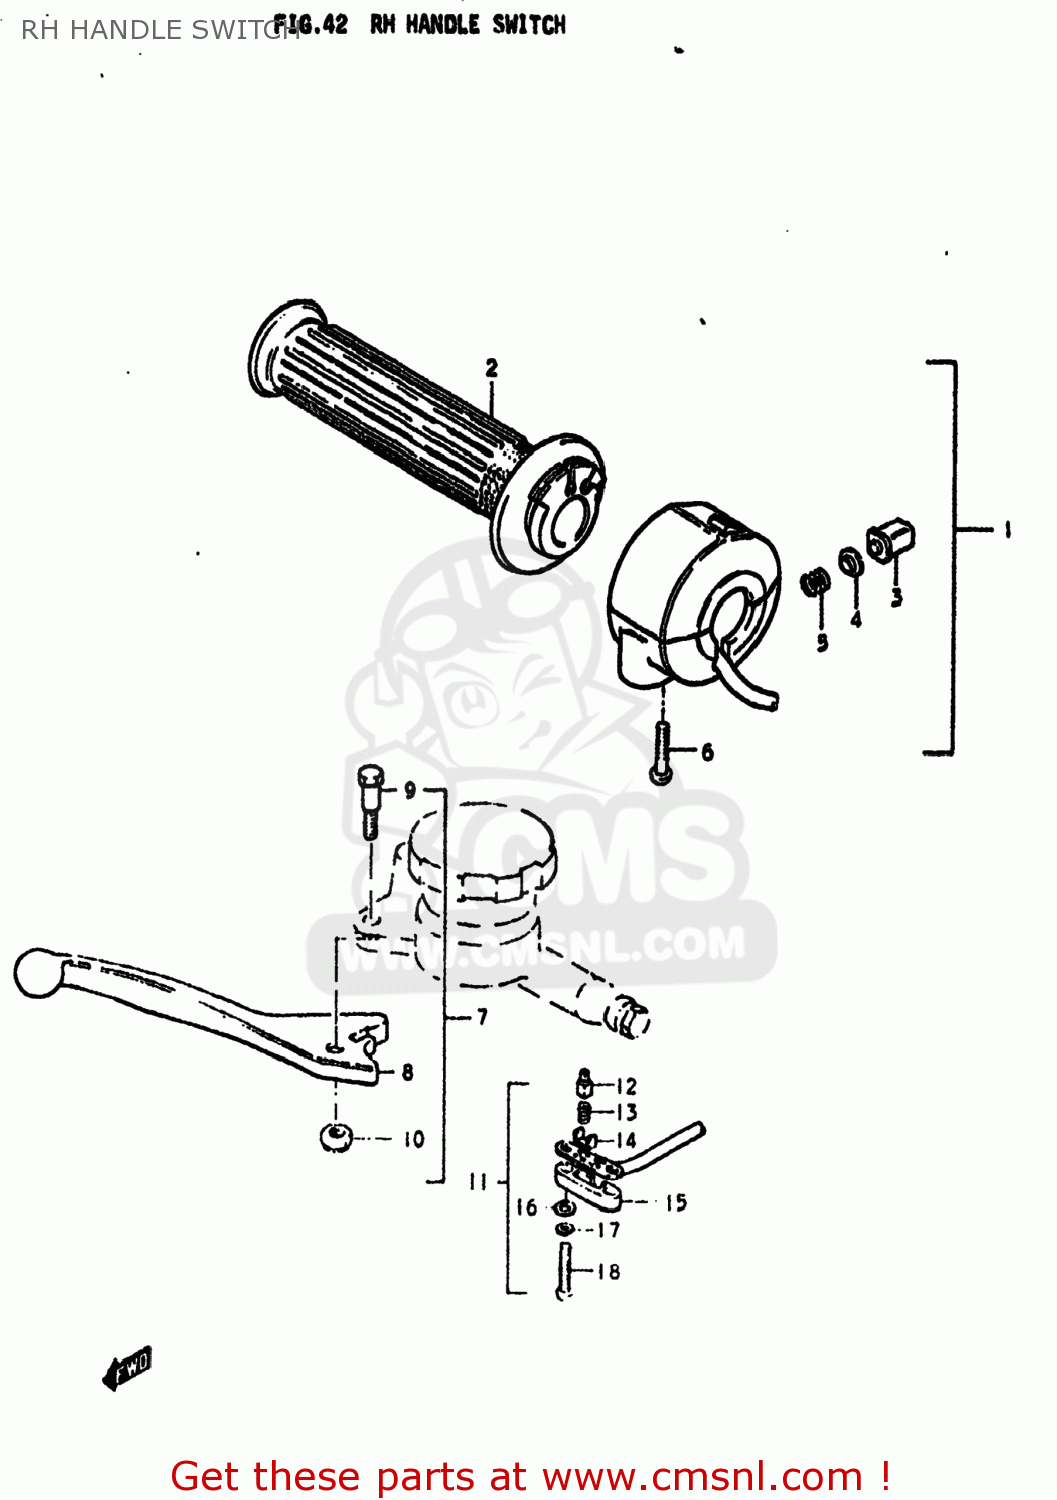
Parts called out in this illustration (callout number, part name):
1	CASE ASSEMBLY,THROTTLE
2	GRIP,THROTTLE
3	BUTTON,HORN
4	CONTACT
5	SPRING
6	SCREW
7	LEVER ASSEMBLY,BRAKE
8	LEVER,BRAKE
9	BOLT,LEVER
10	NUT 6MM
11	SWITCH ASSY,STOP
12	HOLDER
13	SPRING
14	PLATE
15	COVER,FR BK TERMINAL BASE
16	WASHER
17	LOCK WASHER
18	SCREW
